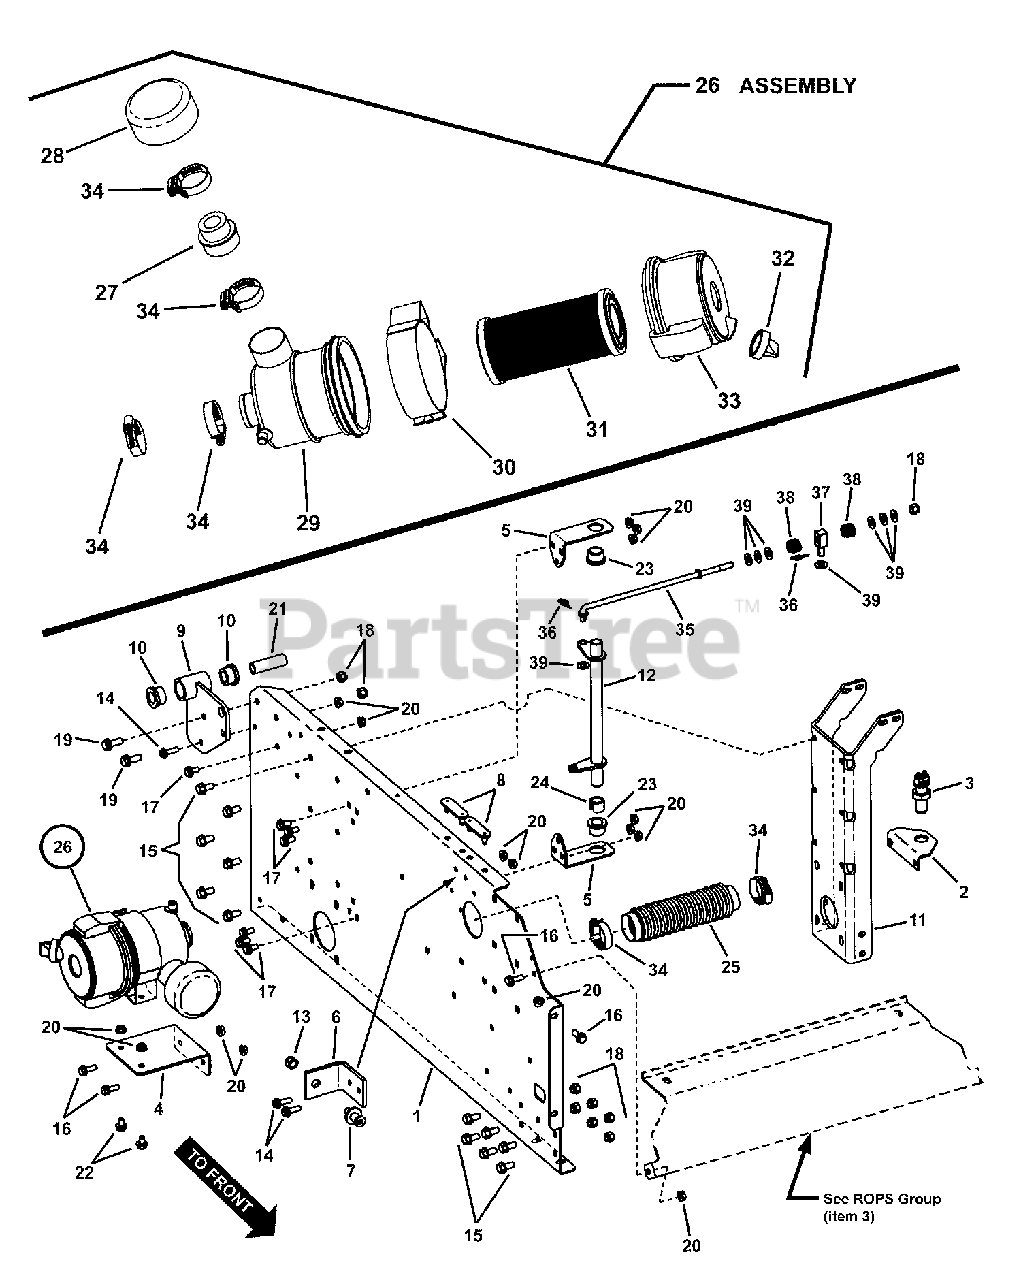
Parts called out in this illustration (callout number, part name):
1	FRAME, Rear RH (Red)
1	FRAME, Rear, RH (Green)
2	BRACKET, Speed Sensor (weldment)
3	SENSOR, Speed
4	BRACKET, Air Filter
5	BRACKET, Transmission Shift
6	BRACKET, Bed Latch
7	PIN, Bed Latch Striker (7/16-14 thread)
8	BUMPER, Rubber
9	WELDMENT, Dump Bed Pivot, Red
9	WELDMENT, Dump Bed Pivot (Green)
10	BUSHING, Suspension
11	STIFFENER, CVT Frame (Red)
11	STIFFENER, CVT Frame (Green)
12	WELDMENT, Shifter Shaft
13	NUT, 7/16-14, Hex Nyloc
14	BOLT, 5/16-18 x 1" Hex Flange Lock
15	SCREW, 3/8-16 x 3/4" Hex Washer Self-Tap
16	BOLT, 5/16-18 x 7/8" Hex Flange Lock
17	BOLT, 5/16-18 x 5/8" Hex Flange Lock, GR 5
18	NUT, 3/8-16 Hex Nyloc
19	BOLT, 3/8-16 x 1" Hex Flange Lock, GR 5
20	NUT, 5/16-18 Hex Flange Lock, GR 5
21	SLEEVE, Suspension
22	BOLT, 5/16-18 x 1/2" Hex Flange Lock
23	BEARING, .750 I.D.
24	RING, Blue
25	FLEX TUBE, 1.75 x 1.75 x 12"
26	ASSEMBLY, Air Filter (Includes Ref. #'s 27 thru 34)
27	RESTRICTER, Air Cleaner
28	PRECLEANER, Air Filter
29	HOUSING, Air Filter
30	BRACKET, Air Filter Mounting
31	ELEMENT, Air Filter
32	VALVE, Air Filter Drain
33	CAP, Air Filter
34	CLAMP, Hose
35	ROD, Transmission Shift (3/8-16 thread)
36	COTTER PIN, 3/8 Self Lock
37	SWIVEL, 3/8 w/thru hole
38	SPRING, Friction Pack
39	WASHER, 3/8" SAE Flat
